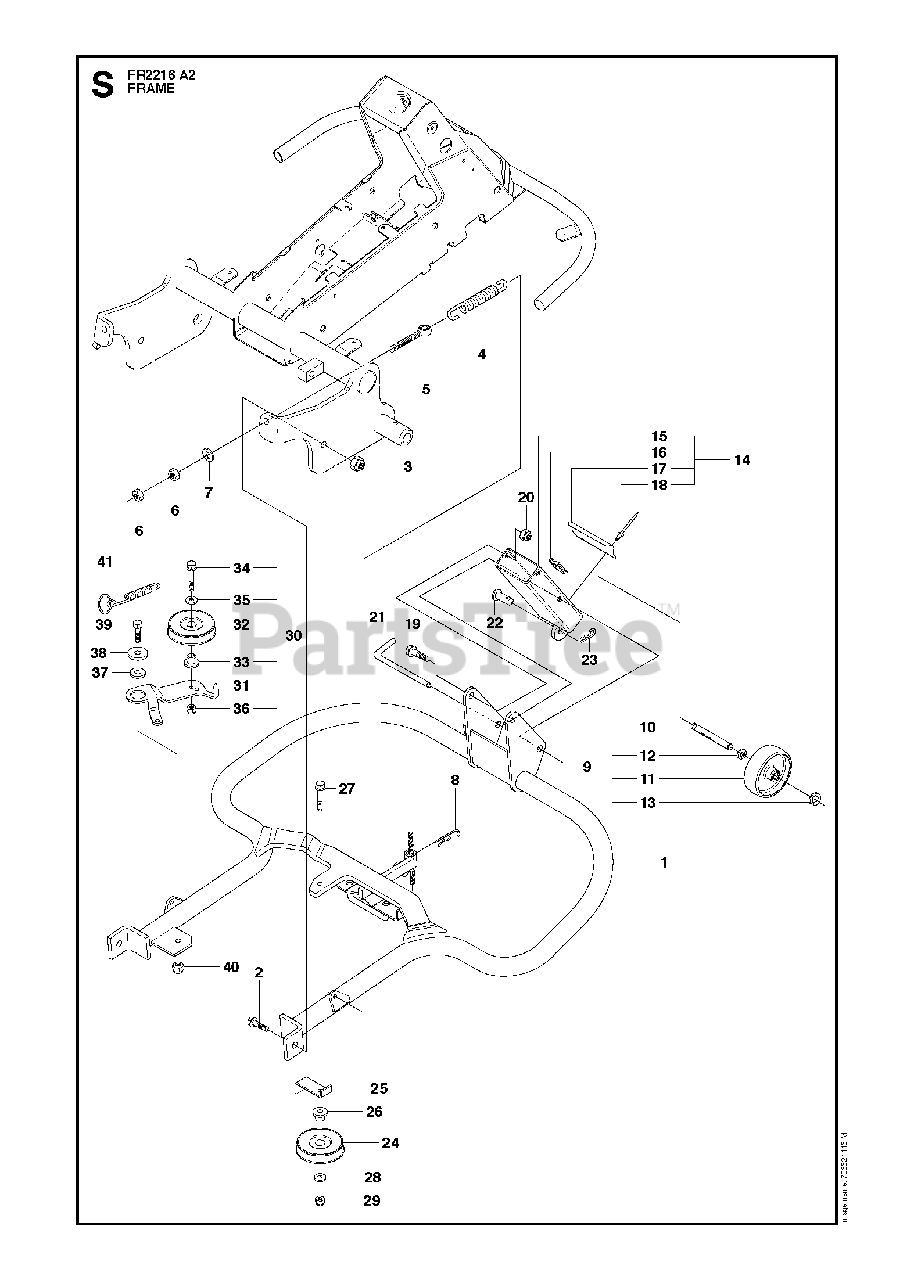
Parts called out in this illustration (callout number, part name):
7	WASHER
9	WHEEL ASSY
13	RETAINING RING
14	LINK ASSY
20	LOCKNUT M8
29	LOCKNUT M8
30	BELT TENSIONER ASSY
36	LOCKNUT M8
